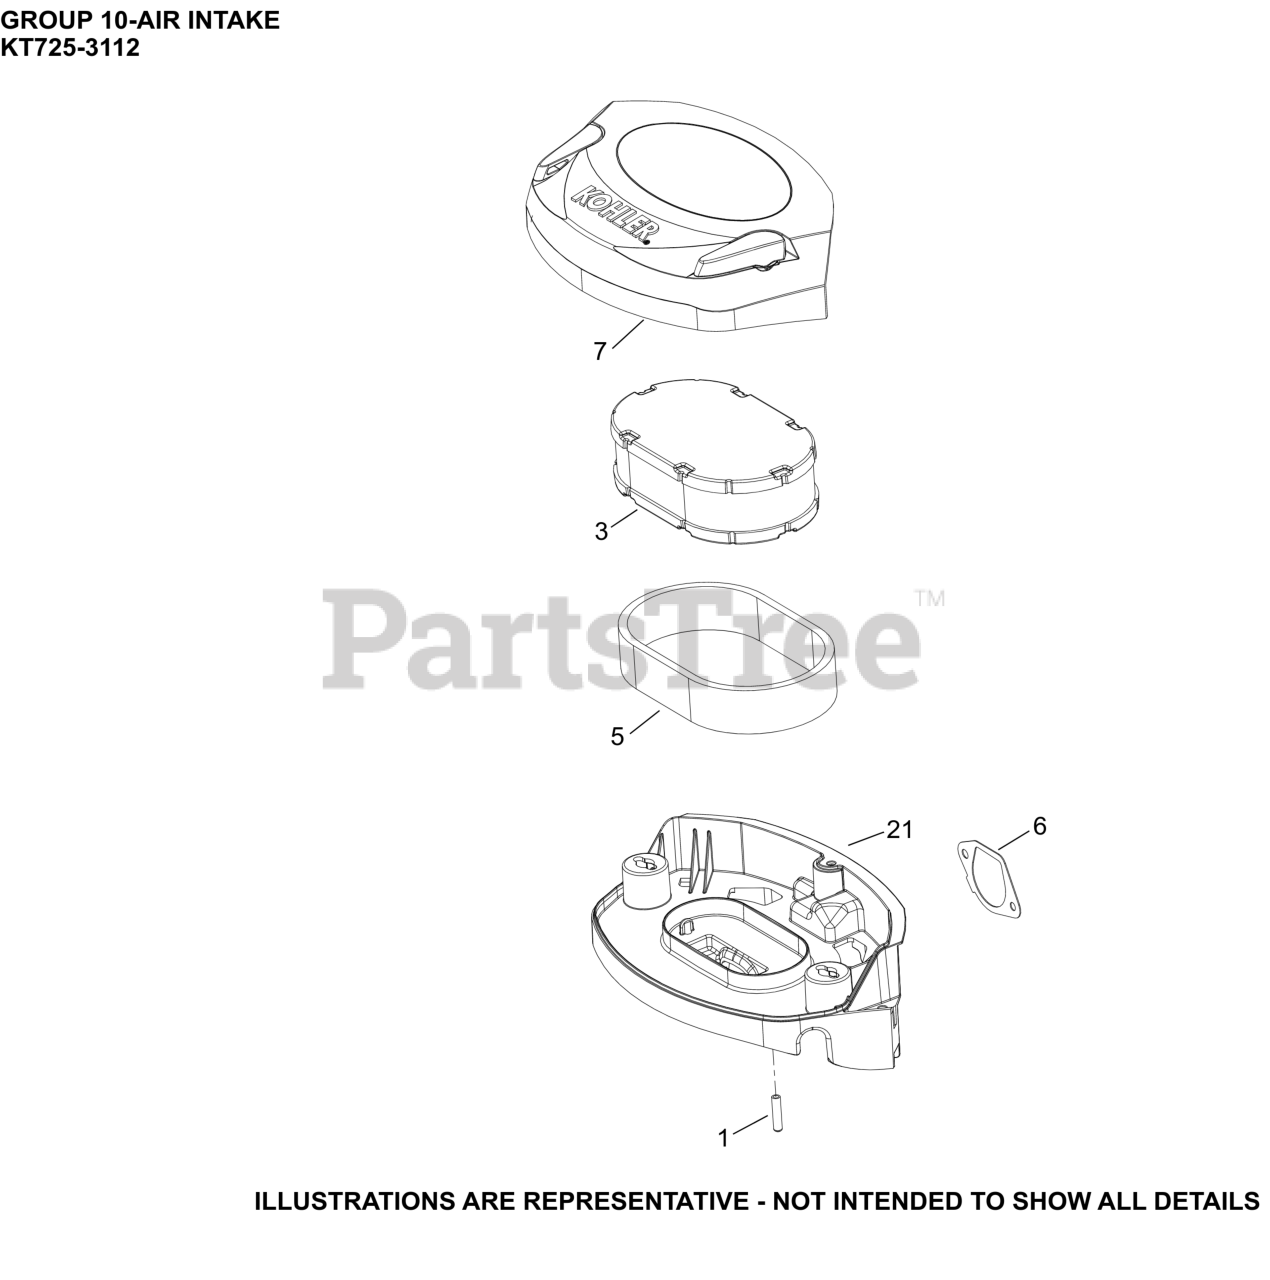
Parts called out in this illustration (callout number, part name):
1	CAP, MASKING
3	ELEMENT, AIR FILTER
5	ELEMENT, PRE-CLEANER
6	GASKET, AIR CLEANER BASE
7	COVER ASSEMBLY, AIR CLEANER
21	BASE ASSEMBLY, AIR CLEANER
